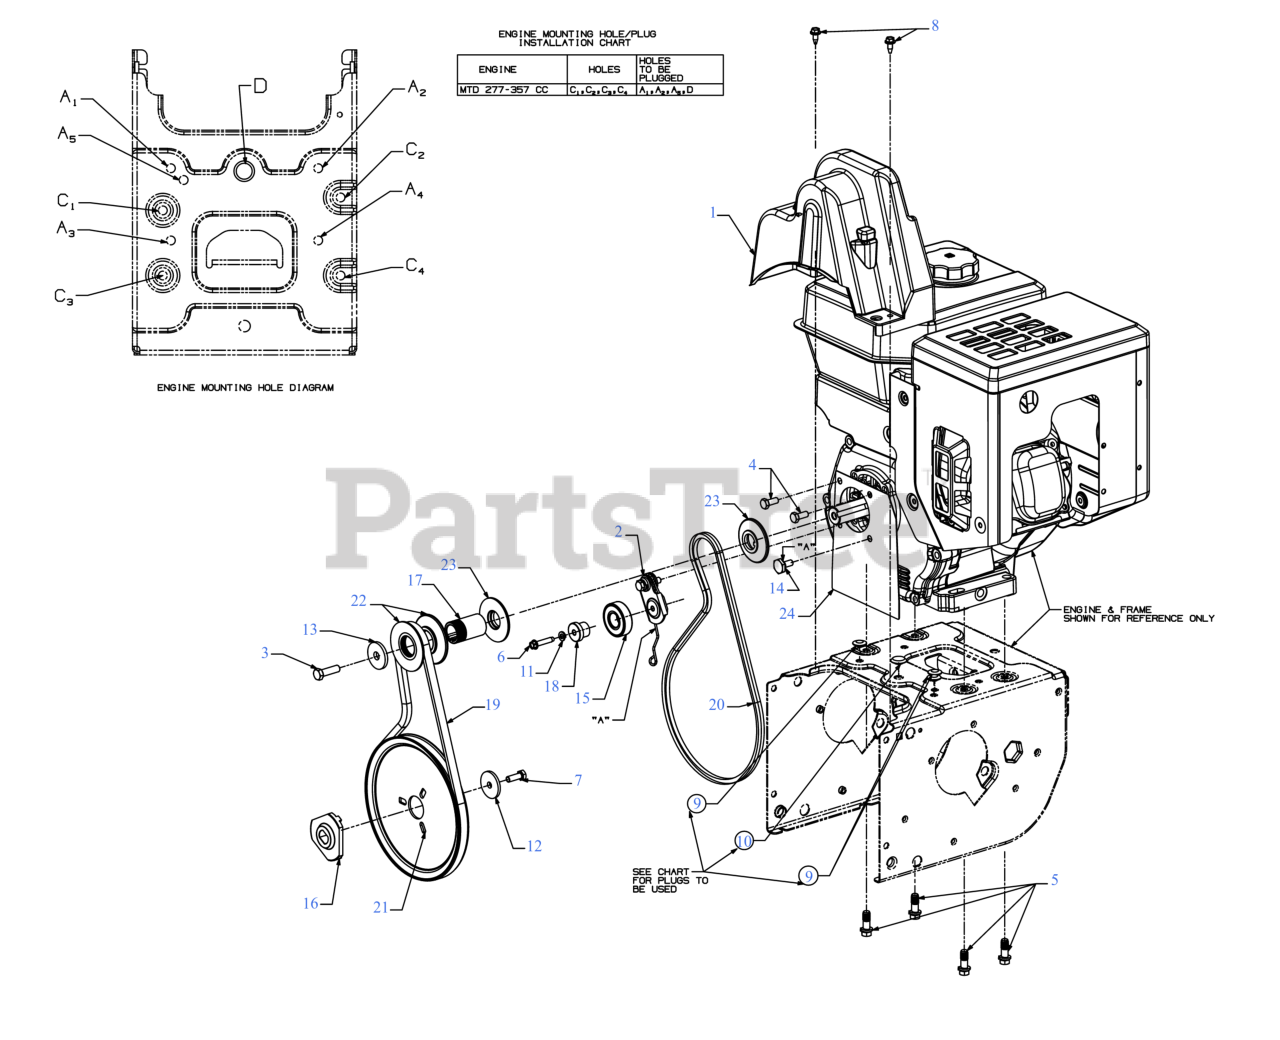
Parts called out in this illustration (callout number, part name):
1	BELT COVER (LARGE BLOCK)
3	SCREW 3/8-24X1.25
4	SCREW 5/16-24 x .750 GR5
5	SCREW 3/8-16 x 1
6	SCREW 1/4-20 x 1.25
7	SCREW 5/16-24 x .875 GR5
8	SCREW 1/4-20X.625
9	PLUG-3/8 DIA ID x 3/32
10	PLUG-1/2 ID x 3/32
11	LOCK WASHER
12	FLAT WASHER
13	FLAT WASHER .45 x 1.5 x .172 HT
14	SHOULDER SCREW
15	BALL BEARING
16	ADAPTER PULLEY .75 DIA W/DD
17	PULLEY SPACER
18	SHOULDER SPACER
19	BELT-.500 x 37.00
19	Cub Cadet AUGER BELT
19	Genuine Factory Parts AUGER BELT
20	BELT-3L x 36.64 LG
21	AUGER PULLEY
22	HALF PULLEY 4L V x 2.6 OD
23	HALF PULLEY 3/8-V x 2.2
24	ENGINE PLATE (FRONT COVER)
